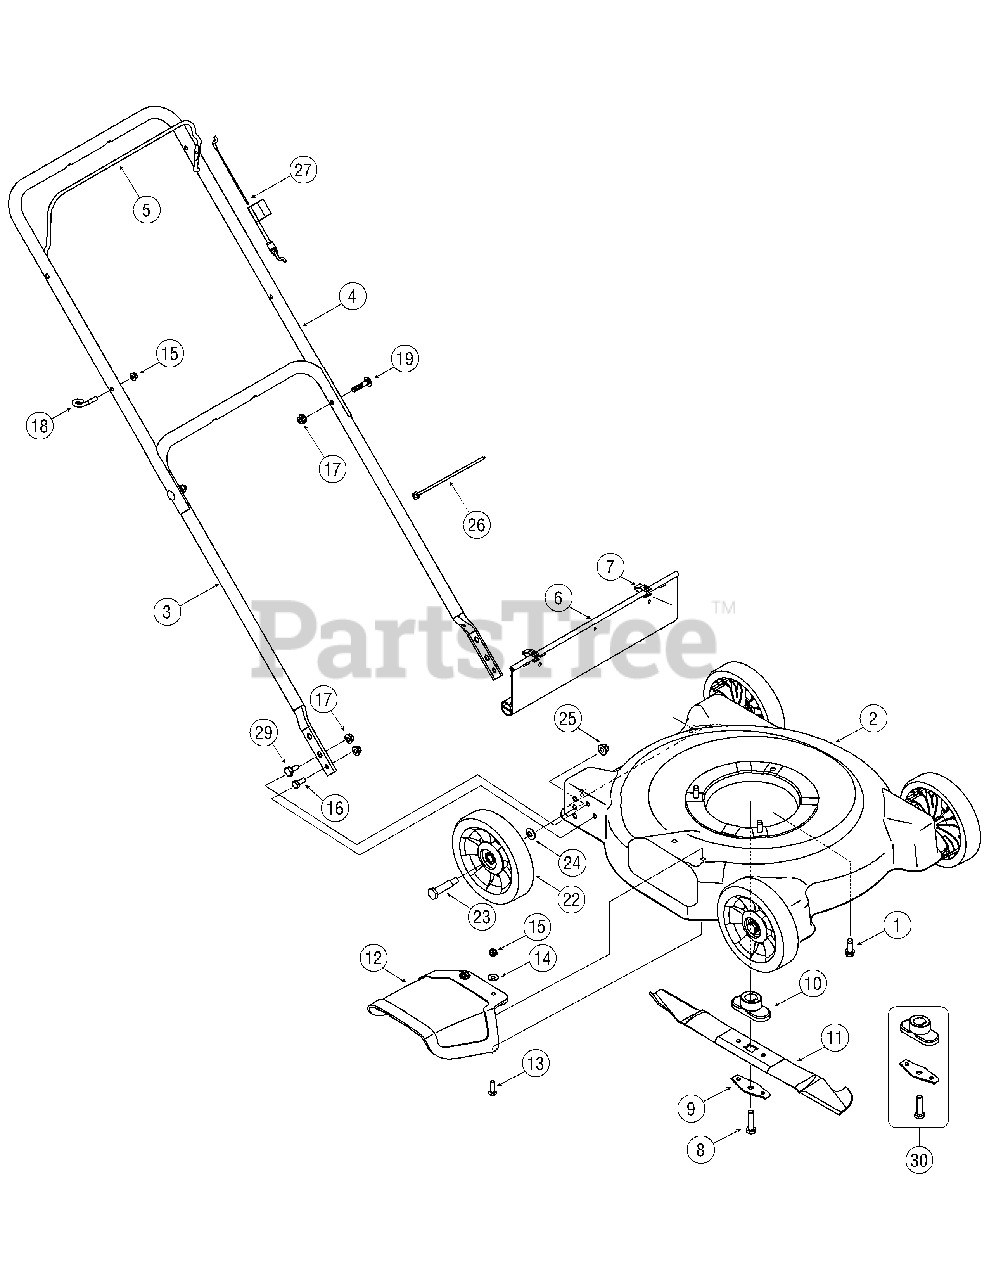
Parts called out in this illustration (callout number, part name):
1	Hex Wash HD Tap Scr 3/8-16 x .88
2	20" Deck w/o sprig logo
4	Upper Handle
5	Blade Control Handle
6	Rear Flap
7	Hinge Clip
8	Hex Bolt 3/8-24 x 1.5" Lg. (Gr 8)
9	Blade Bell Support
10	Blade Adapter
11	Blade, Centre Star, 20"
12	Fixed Side Chute
13	Carriage Bolt 1/4-20 x 1.00" Lg.
14	Flat Washer .28 ID x .74 OD x .063
15	Flanged Lock Nut 1/4-20 Gr. F Nylon
16	Hex Bolt 5/16-18 x .75" Lg. Gr. 5
17	Flanged Lock Nut 5/16-18 Gr. F Nylon
18	Rope Guide Bolt
19	Carriage Bolt 5/16-18 x 1.50 Gr. 2
22	Front Wheel Ass’y 7" Star Diamond Grey
23	Shoulder Screw .498" DIA. x 1.64
24	Cupped Washer .375 ID x .870 OD x .063
25	Flanged Lock Nut 3/8-16 Gr. F Nylon
26	Cable Tie
27	Control Cable 37.25" Lg. (B&S)
29	Shoulder Screw, 3/8-16 x .428
30	Blade Adapter Kit
